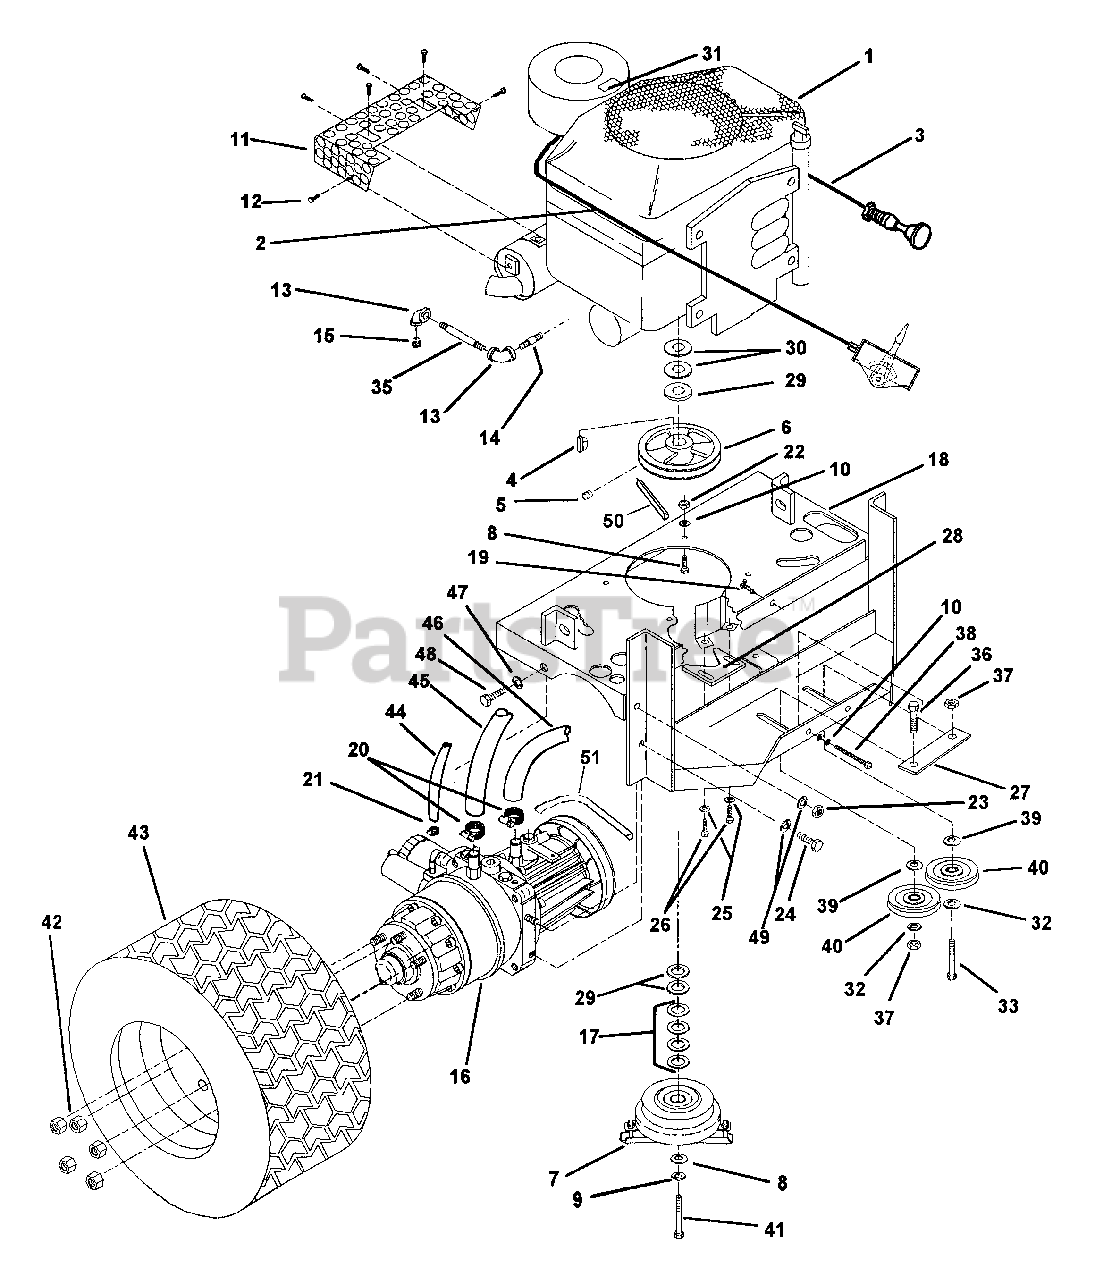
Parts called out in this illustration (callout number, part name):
1	* ENGINE, 20 HP KOHLER, VERTICAL SHAFT
2	CABLE, THROTTLE
3	CABLE, CHOKE
4	KEY, WOODRUF, 1/4" X 3/4"
5	SET SCREW, SOCKET HD., 5/16-18 X 3/8"
6	PULLEY, 1-1/8" BORE
7	CLUTCH, ELECTRIC, 1" BORE
8	CAP SCREW HH 5/16-24 X 1-1/2 GR 5
9	LOCK WASHER, 7/16" SPLIT SPRING
10	LOCK WASHER, 5/16" SPLIT SPRING
11	MUFFLER GUARD
12	SCREW, SHEET METAL, #8-32 X 1/2"
13	ELBOW, 3/8, 90, SCH 40 CAST IRON
14	NIPPLE 3/8" CLOSE SCH. 40 BLACK
15	PLUG, PIPE 3/8"
16	UNISTAT TRANSMISSION
17	WASHER, 10 GA. 1" BORE
18	MOTOR MOUNT WELDMENT
19	BLIND HOLE KURLY
20	CLAMP, HOSE 1/2" STAINLESS
21	CLAMP, 1/4 HH SCREW 1/4 MI
22	NUT, 5/16-24 UNF, GR. 5 PLATED
23	NUT, HEX HEAD, 1/2 13 UNC 2B
24	CAP SCREW, HEX HEAD, 1/2-13 X 1-1/4 LG
25	WASHER, FLAT, STD, STEEL, 1/4"
26	CAP SCREW, HH 1/4-20 X 3/4" GR. 5
27	PLATE, STAGGER
28	PLATE, CLUTCH STOP
29	WASHER, 16 GA. 1-1/8" I.D.
30	WASHER, 10 GA. 1-3/16 ID
31	DECAL," PERIODICALLY CLEAN
32	WASHER, 1/2" NOM, TYPE B NARROW
33	CAP SCREW, HEX HD., 1/2-13 X 2 GR.5
35	NIPPLE, 3/8" X 4" SCH 40
36	STUD, ADJUSTABLE
37	LOCKNUT, 1/2-13, NYLOC
38	CAPSCREW, HX, 5/16-18 X 3",G2 FL-TH
39	WASHER, FLAT, STD, 1/2"
40	PULLEY, V-IDLER, 4.48 O.D.
41	CAP SCREW, 7/16-20 X 3" GR. 5
42	WHEEL LUG NUT: 7/16-20, PLTD.
43	TIRE/WHEEL ASSEMBLY, 23-9.5 X 12
44	HOSE, 3/8 ID X 15" LG. R.H. SIDE
44	HOSE, 3/8 ID X 38" LG. L.H. SIDE
45	HOSE, 5/8 I.D. X 12" LG
46	HOSE, 5/8 I.D. X 7" LG
47	LOCK WASHER, SPLIT SPRING: 5/8" X-H
48	CAP SCREW, 5/8-11 X 1-1/2
49	LOCKWASHER, SPLIT SPRING, 1/2"
50	BELT, KEVLAR, AK-42 (PRIMARY DRIVE)
51	BELT, KEVLAR, AK-75 (SECONDARY DRIVE)
